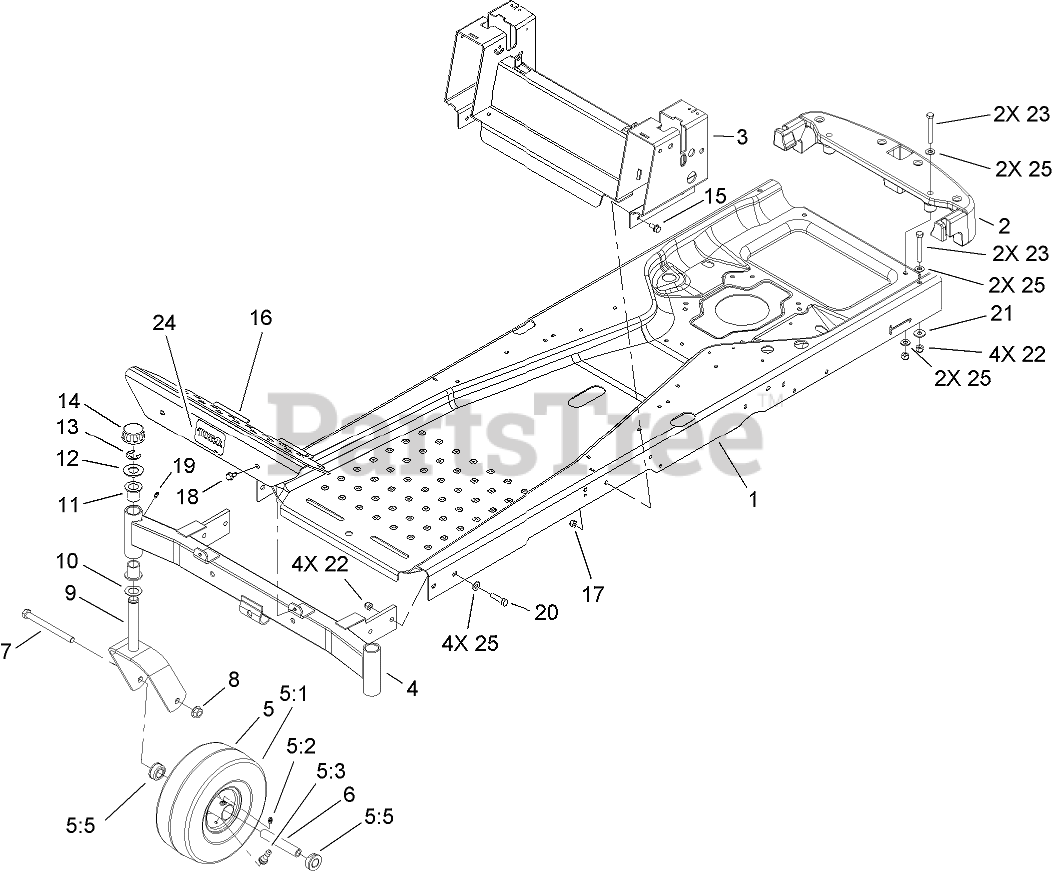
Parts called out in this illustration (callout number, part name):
1	FRAME
2	BUMPER-REAR
3	SEAT CONTROL ASM
4	FRONT AXLE ASM
5	CASTER WHEEL ASM (Kenda)
5:1	TIRE-SMOOTH
5:2	FITTING-GREASE
5:3	STEM-VALVE
5:5	BUSHING-FLANGE
6	BUSHING-SPANNER
7	SCREW-HH
8	NUT-HF
9	CASTER FORK ASM
10	WASHER-THRUST
11	BEARING-FLANGED
12	WASHER
13	RING-RETAINING, EXT
14	CAP-HUB
15	SCREW-HHF
16	FOOTREST
17	NUT-LOCK, NI
18	SCREW-HWH
19	FITTING-GREASE
20	SCREW-HH
21	WASHER-HARDENED
22	NUT-LOCK, NI
23	SCREW-HH
24	DECAL
25	WASHER-FLAT
